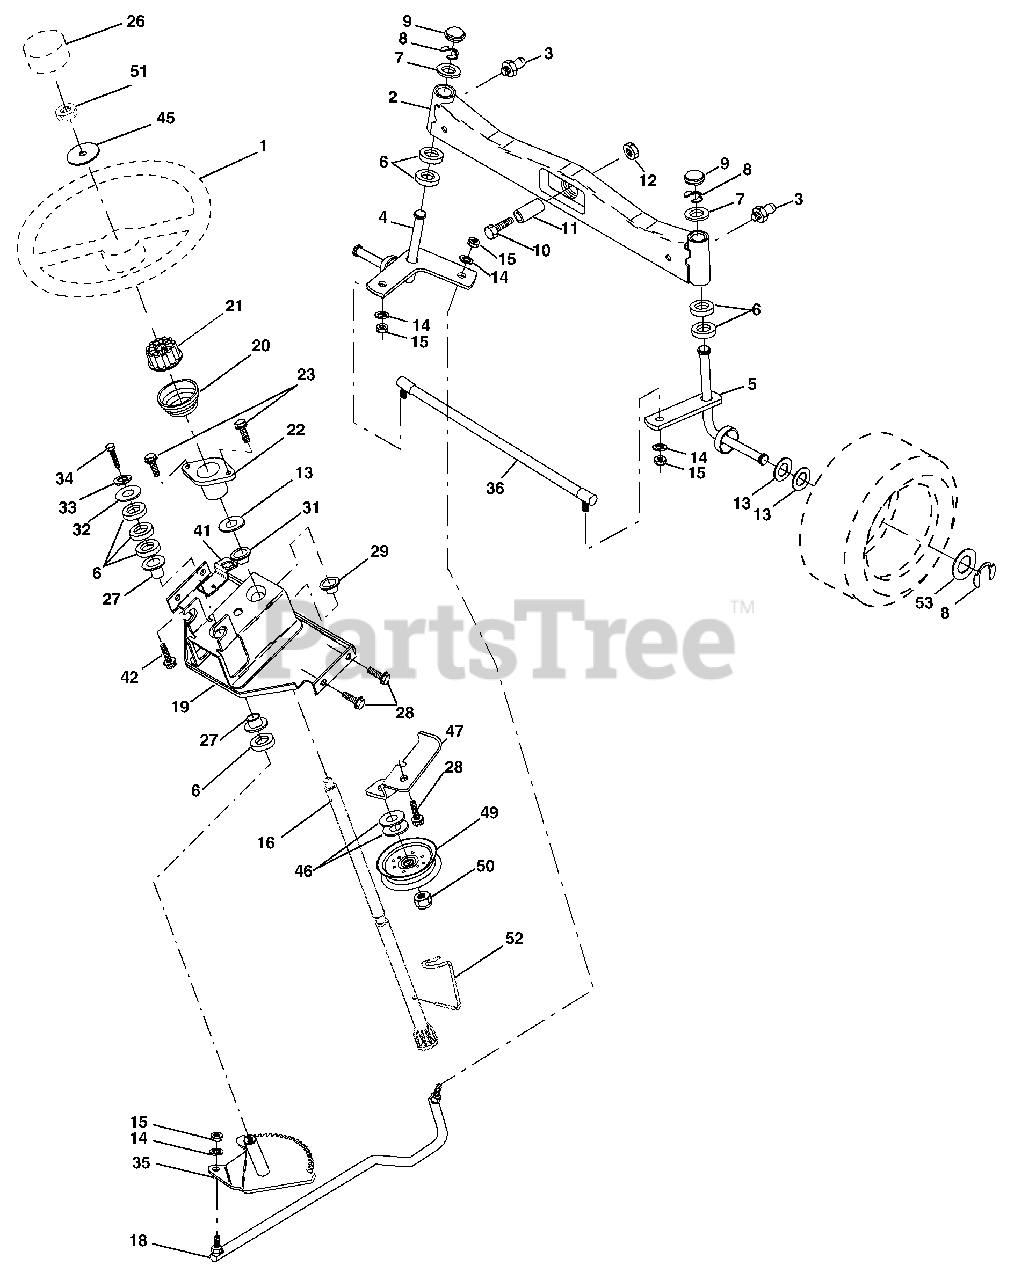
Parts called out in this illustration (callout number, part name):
1	Wheel, Steering
2	Axle Asm., Front
3	Fitting, Grease
4	Spindle Asm, LH
5	Spindle Asm., RH
6	Bearing, Race Thrust Harden
7	Washer 25/32 x 1-5/8 x 16 Ga.
8	Ring Klip #T5304-75
9	Cap, Spindle
10	Bolt, Fin Hex 5/8-11 x 2-3/4
11	Spacer Bearing Axle Front
12	Nut, Lock Flange 5/8-11 Unc
13	Washer 25/32 x 1-1/4 x 16 Ga.
14	Washer, Lock Hvy Hlcl Spr 3/8
15	Nut, Crownlock 3/8-24
16	Shaft Asm., Steering
18	Draglink, Ball Joint Solid Vgt
19	Support Asm., Steering Vgt
20	Boot, Steering
21	Adapter, Wheel Steering
22	Bushing, Strg. Blk
23	Screw
26	Cap , Wheel Steering
27	Bearing, Col. Strg.
28	Screw 3/8-16 x 3/4
29	Bearing, Flange
31	Bushing, Nyliner Snap
32	Washer 11/32 x 1 x 10 Ga.
33	Washer, Lock Hvy Hlcl Spr 5/16
34	Bolt, Fin Hex Hd 5/16-18 x 3/4
35	Gear, Sector Steering
36	Tie Rod
41	Bracket Switch Interlock VGT 97
42	Screw Thdrol 5/16-18 x 1/2 Tyt
45	Washer 9/16 ID x 2-3/8 OD 12 G zin
46	Washer Flat 13/32 x 1 x 10 Ga.
47	Bracket Asm. Idler Stationary
49	Pulley Idler Flat
50	Nut Lock Flg 3/8-16 unc
51	Nut Hex Jam Toplock 1/2-20 unf
52	Clip Steering
53	Washer Hardened
